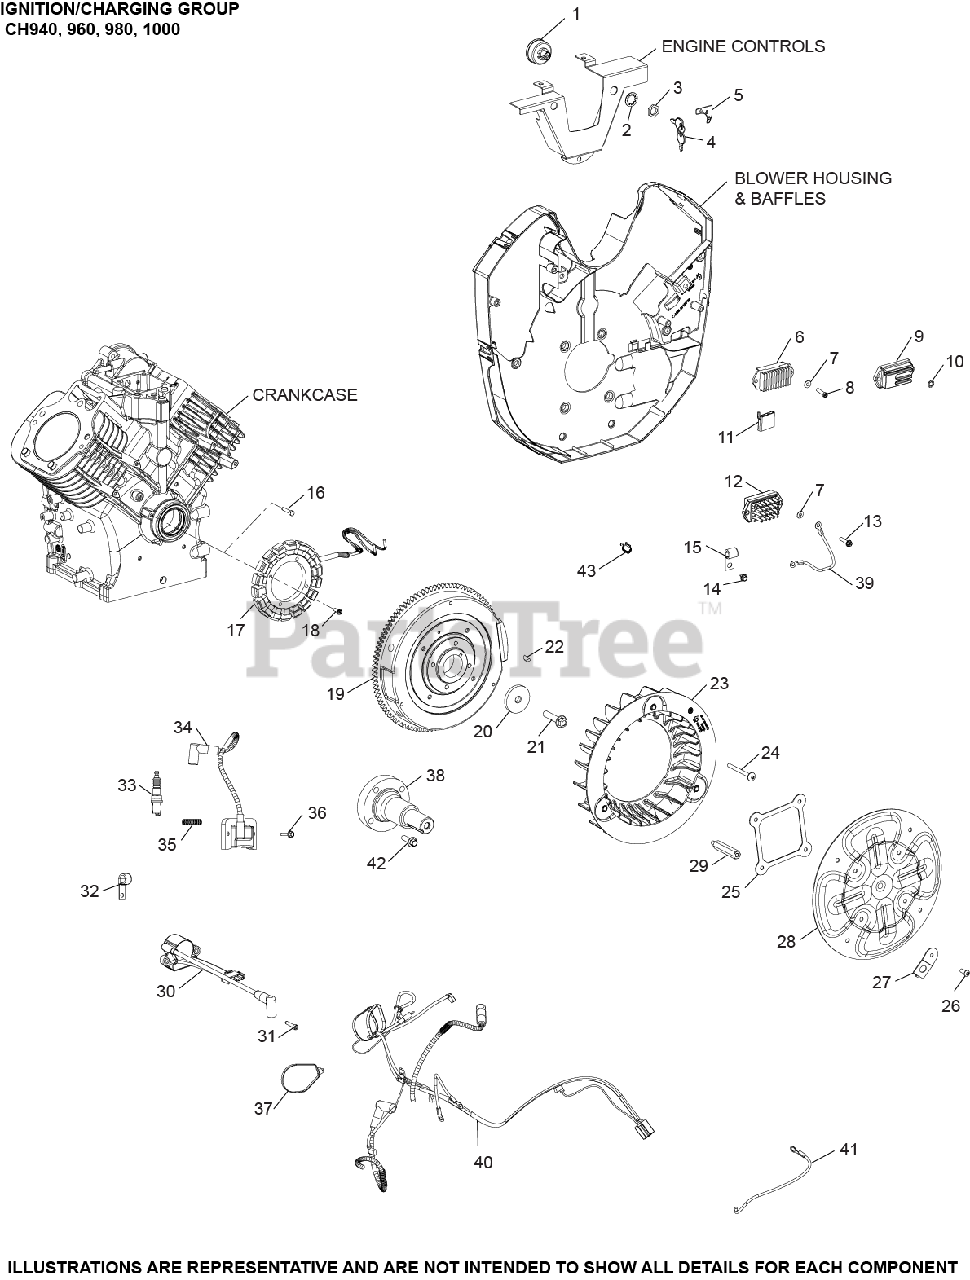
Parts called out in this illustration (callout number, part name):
1	SWITCH ASSEMBLY, KEY
2	WASHER, INTERNAL TOOTH
3	NUT, KEY SWITCH
4	KEY, SET OF 2
5	DECAL, KEYSWITCH
6	REGULATOR, RECTIFIER (20/25 AMP) USE 25 403 32-S
10	WASHER, INT TOOTH LOCK 1/4"
11	CONNECTOR
13	SCREW, HEX FLANGE HI-LO
14	SCREW, THREAD FORMING
15	CLIP, CABLE
17	KIT, 25 AMP STATOR ASSY.
18	SCREW, THREAD FORMING
19	FLYWHEEL ASSEMBLY
20	WASHER, FLAT 13/32"
21	SCREW, FLG M10X1.5X45 - (#25086361S)
22	KEY, 3/16" X 5/8"
23	KIT, FAN AND SPACERS
24	SCREW, TRS HD M6X1.0X65
25	STIFFENER, GRASS SCREEN
27	PLATE, GRASS SCREEN WASHER
28	KIT, GRASS SCREEN
29	STUD, GRASS SCREEN
30	MODULE, SPARK ADVANCE (DSAI) ASSEMBLY
32	CLIP, CABLE
33	PLUG, SPARK
35	SLEEVE, CORRUGATED
36	SCREW, THREAD FORMING
37	TIE, CABLE
40	HARNESS,WIRING (DSAI,KEYSWITCH)
41	LEAD, B+ TO STARTER SOLENOID
